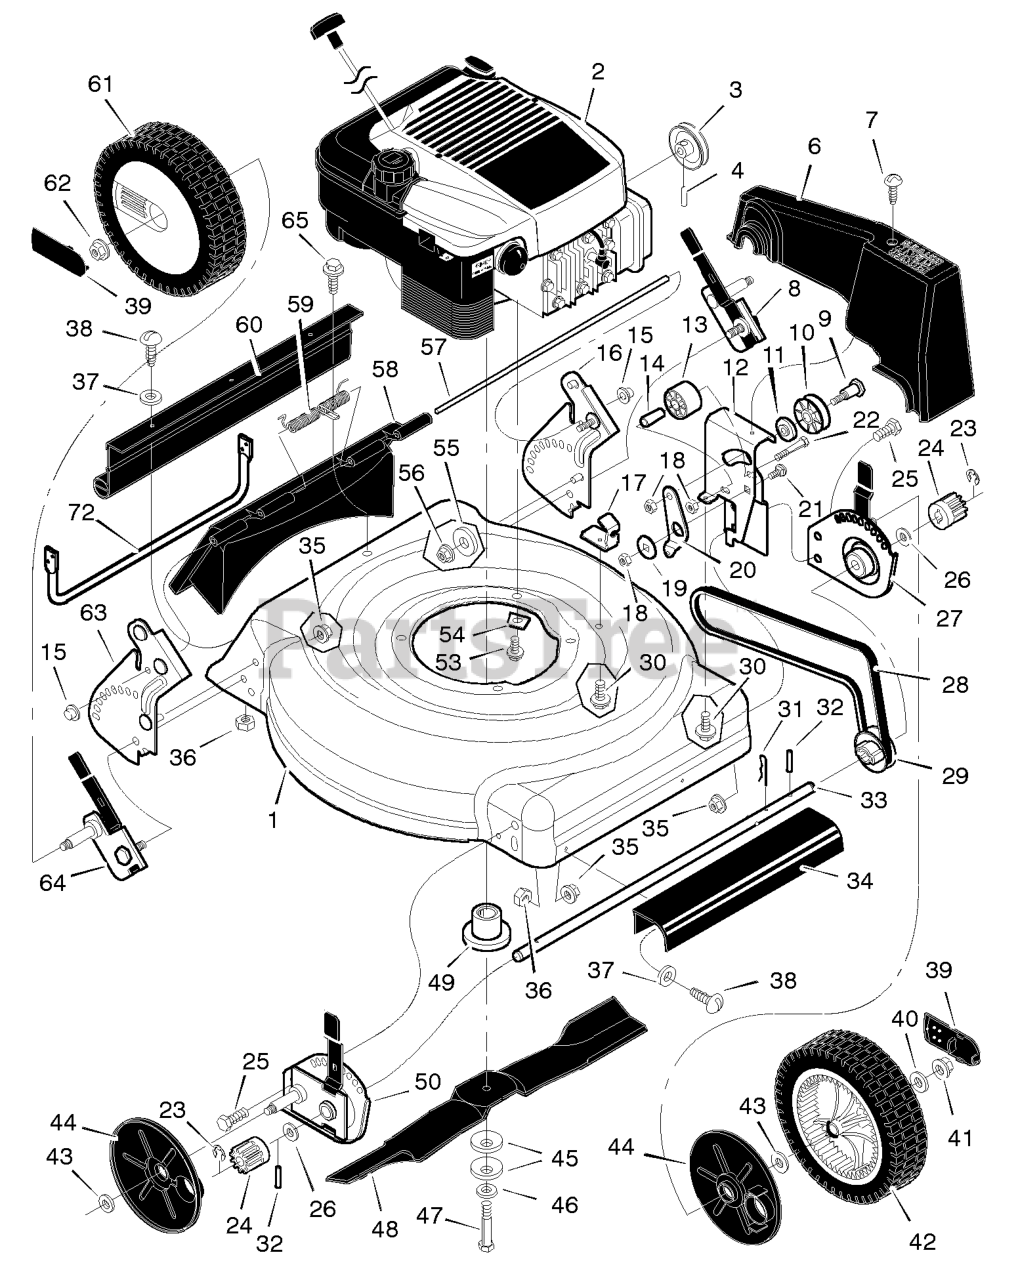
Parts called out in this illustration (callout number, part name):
1	Housing
2	Engine
3	Pulley, Engine
4	Pin, Spring
6	Cover, Belt
8	Adjuster, Left Height
9	Bolt, Shoulder
12	Bracket, Idler Support
13	Pulley, Idler
14	Bearing
15	Push On Cap
16	Bracket, Left Handle
17	Bracket, Cable
18	Nut, Hex
20	Arm, Idler
21	Bolt, Carriage
22	Bolt, Shoulder
23	E- Ring
24	Gear, Pinion
25	Bolt
27	Adjuster, Left Front Height
29	Pulley, Axle
31	Pin, Hair
32	Pin, Spring
34	Cover, Axle
35	Nut, Flange
36	Nut, Hex
39	Hub Cap
40	Washer
41	Nut, Flange
42	Wheel, Drive
44	Cover, Dust
45	Washer, Belleville
49	Adapter, Blade
50	Adjuster, Right Front Height
53	Bolt, Engine
54	Support, Engine
55	Washer
56	Nut, Flange
57	Rod, Pivot
58	Door, Rear
60	Deflector, Rear
61	WHEEL & TIRE ASSEMBLY, White, 8"
62	Nut, Flange
63	Bracket, Right Handle
64	Adjuster, Right Height
72	Guard, Rear
